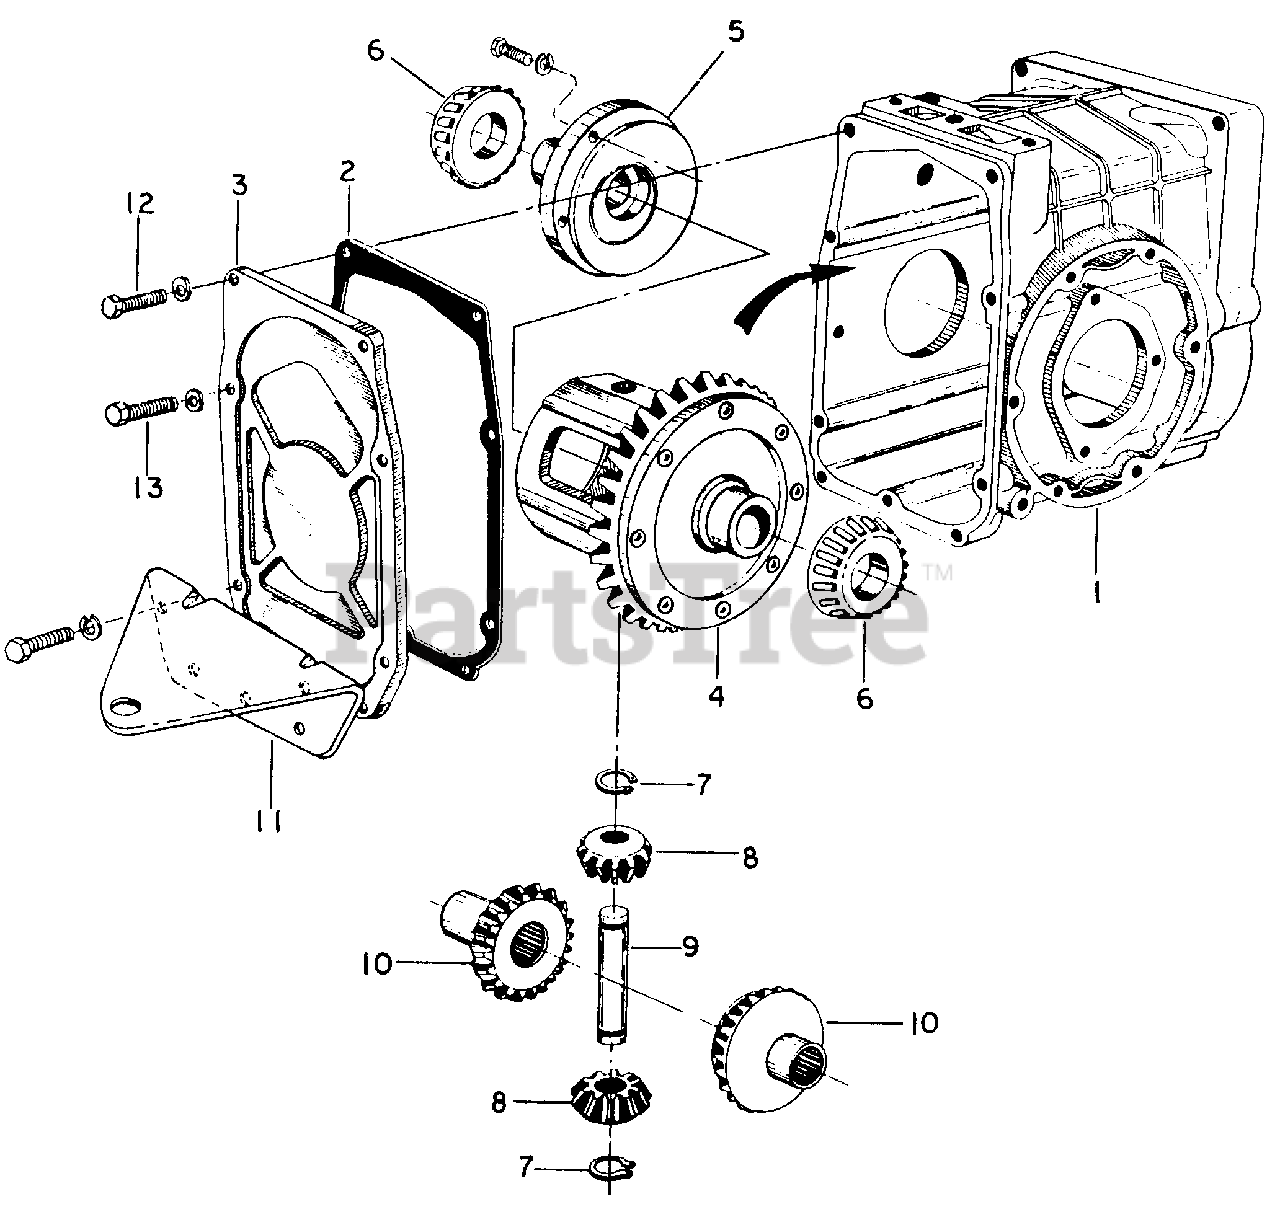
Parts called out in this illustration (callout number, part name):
1	Housing Assy, Rear w/Needle Bearing
2	Gasket, Rear Cover Plate
3	Plate, Rear Cover
4	Gear Assy, Ring w/Case
5	Plate, Diff Flange
6	Bearing Assy, Differential Cone
7	Ring, .616 Hvy Ext Ret
8	Pinion, Differential -10T
9	Shaft, Cross
10	Gear, Side -16T
12	Bolt, 3/8 X 5/8 Type 5
13	Bolt, 3/8 X 3/4 Type 5
